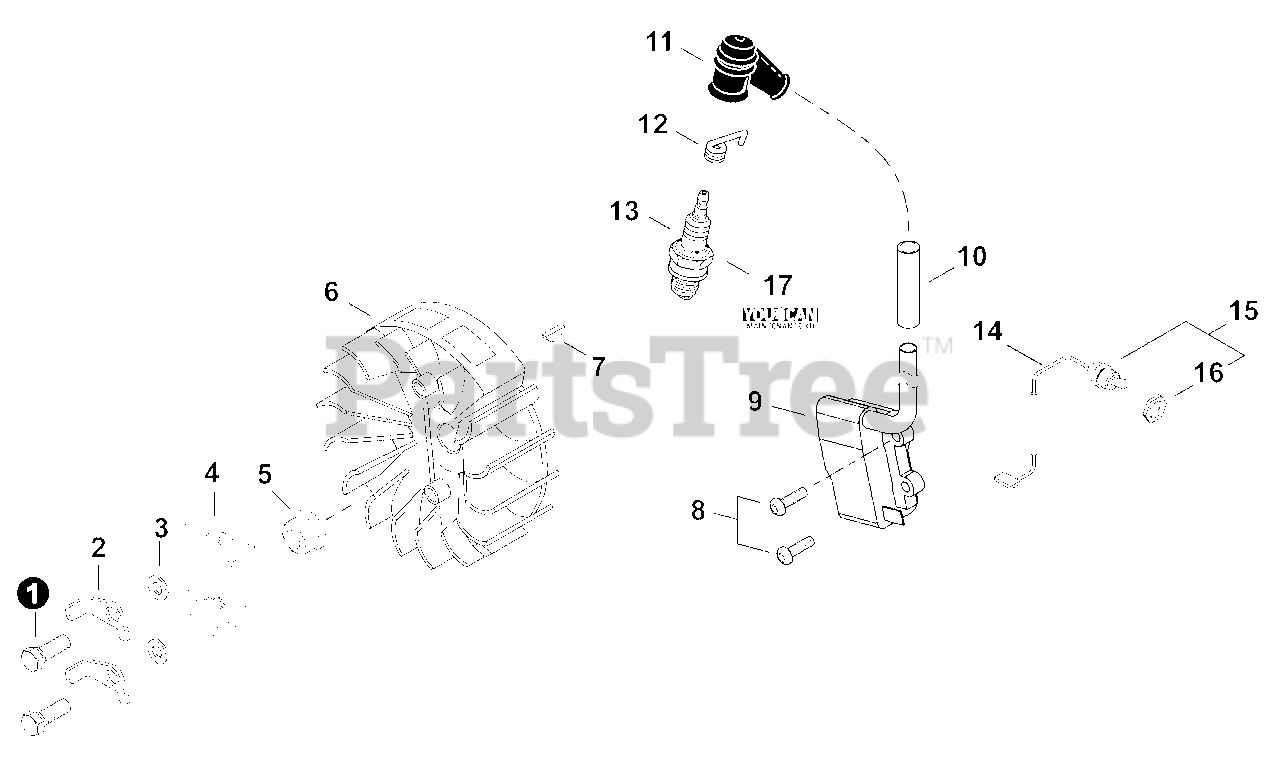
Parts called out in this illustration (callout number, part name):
3	WASHER 6
4	SPRING, TORSION
5	NUT M8×1.0
6	FLYWHEEL
7	KEY, WOODRUFF 3×10
8	BOLT, ADHESIVE M4×20
9	COIL ASSY, IGNITION
10	TUBE, INSULATOR
11	CAP, SPARK PLUG
12	TERMINAL, SPARK PLUG
13	SPARK PLUG - BPMR8Y
14	LEAD - IGNITION
15	SWITCH ASSY, ON-OFF
17	TUNE-UP KIT - YOUCAN™
